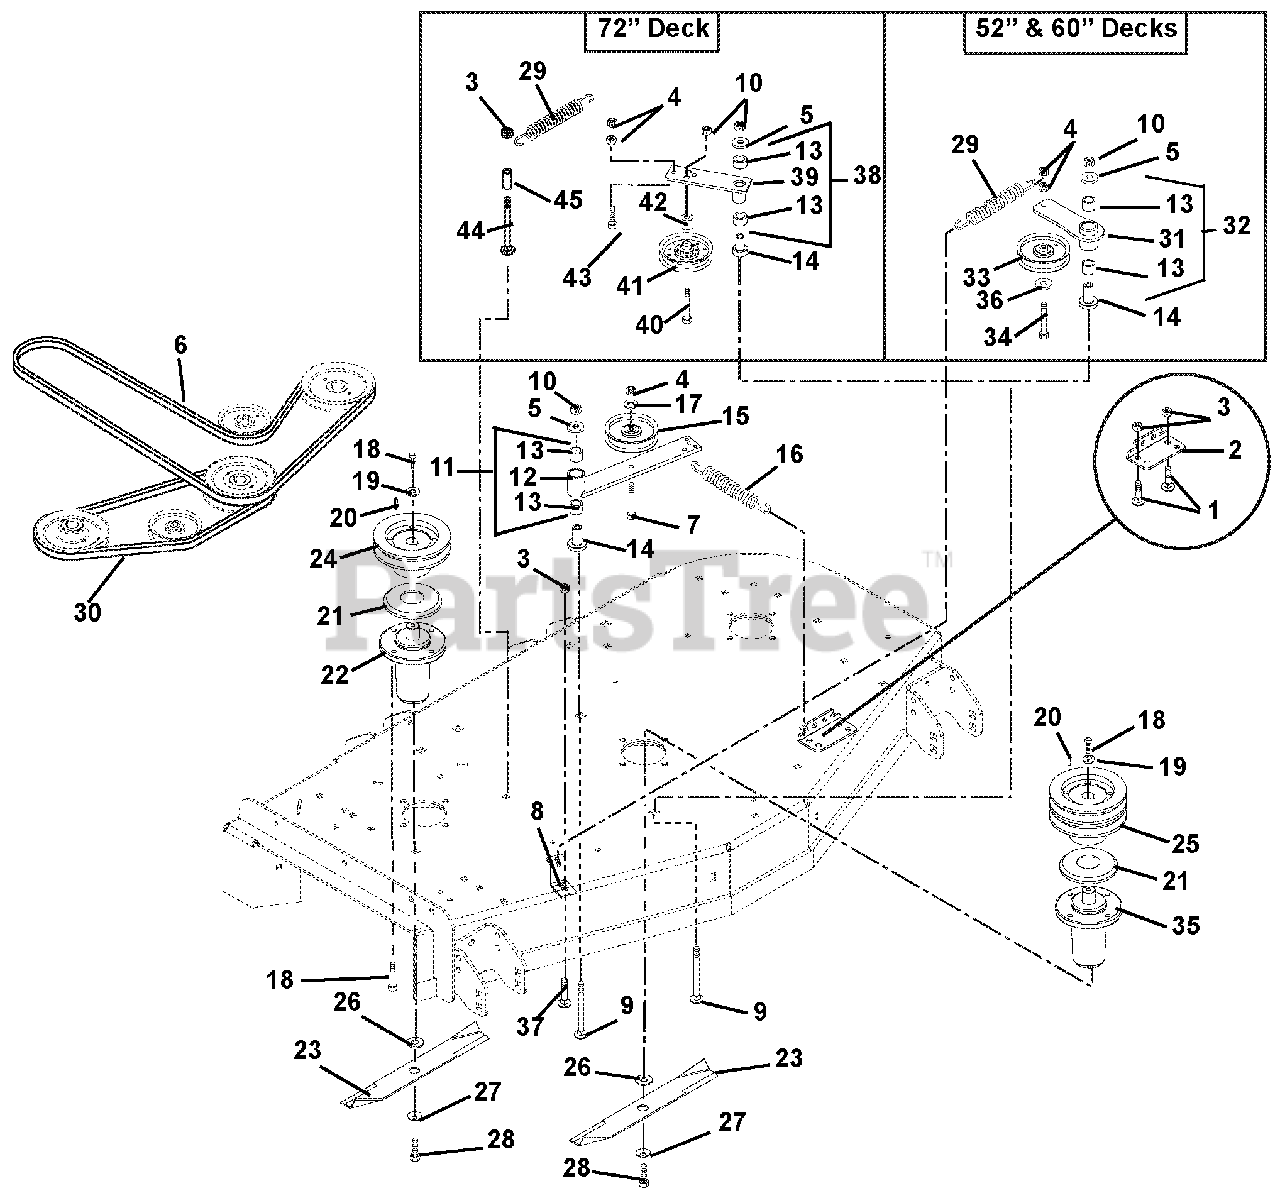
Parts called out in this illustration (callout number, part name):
1	Bolt, Round Head Square Neck .38-16 x .75 Grade 5
2	Bracket, Spring
3	Nut, Locking Top Flange .38-16 (045, 046, 047, 048, 052, 066, 067, 068, 069, 071)
4	Nut, Locking Center .38-16
5	Washer, Flat Steel .531 x 1.25 x .10 (045, 046, 047, 048, 052, 066, 067, 068, 069, 071)
6	V-Belt, B-Section 54.06 x .625 (045, 052, 066, 071)
7	Bolt-Round Head Square Neck .38-16 x 2.75 Grade 5
8	Anchor, Spring
9	Bolt, Round Head Square Neck .50-13 x 3.50 Grade 5
10	Nut, Locking Top Flange .50-13 (045, 046, 047, 048, 052, 066, 067, 068, 069, 071)
11	Assembly, Idler Pivot Arm (Contains Items 12 & 13)
12	Weldment, Idler Pivot Arm
13	Bearing, 1.00 x 1.12 x .75
14	Bearing, Pedestal Powdered Metal
15	Idler, Flat 4.00 x .38 (2.00 W)
16	Spring, Extension
17	Washer, Flat Steel .375 x 1.125 x .065
18	Bolt, Hex .38-16 x 1.00 Grade 8
19	Washer, Flat Steel .406 x 1.50 x .245
20	Key, Square .25 x .25 x 1.00
21	Slinger, Dust
22	Assembly, Maintenance Free Spindle
23	Blade, Mower (049, 053, 070, 072)
24	Weldment, Spindle Sheave 5.00 (045, 052, 066, 071)
25	Sheave, Double (5.25) (045, 052, 066, 071)
26	Washer, Flat .64 x 1.81 x .25
27	Washer, Bellville .63 x 1.625 x .14
28	Bolt, Hex .62-18 x 1.75 Grade 8
29	Spring, Extension
30	V-Belt 5L-Section 49.97 x .672 (049, 053, 070, 072)
31	Arm, Idler Pivot
32	Asm, Idler Pivot Arm (Contains Items 13 and 31)
33	V-Idler, 4.00 x .38
34	Bolt, Hex .38-16 x 2.25 Grade 5
35	Spindle Assembly (Center)
36	Washer, Flat Steel .406 x .812 x .065
37	Bolt, Round Head Square Neck .38-16 x 1.00 Grade 5
38	Assembly, Idler Arm Guard Drive (Includes Items 13 and 39) (049, 053, 070, 072)
39	Weldment, Idler Arm Ground Drive (049, 053, 070, 072)
40	Bolt, Hex .38-16 x 6.00 Grade 5 (049, 053, 070, 072)
41	Idler, Flat Pulley 6.75 x .51 (049, 053, 070, 072)
42	Spacer .513 x .748 x .62 (049, 053, 070, 072)
43	Bolt, Hex .38-16 x 1.25 Grade 5 (049, 053, 070, 072)
44	Bolt, Round Head Square Neck .38-16 x 2.75 Grade 5 (049, 053, 070, 072)
45	Spacer .38 x .625 x 1.50 (049, 053, 070, 072)
